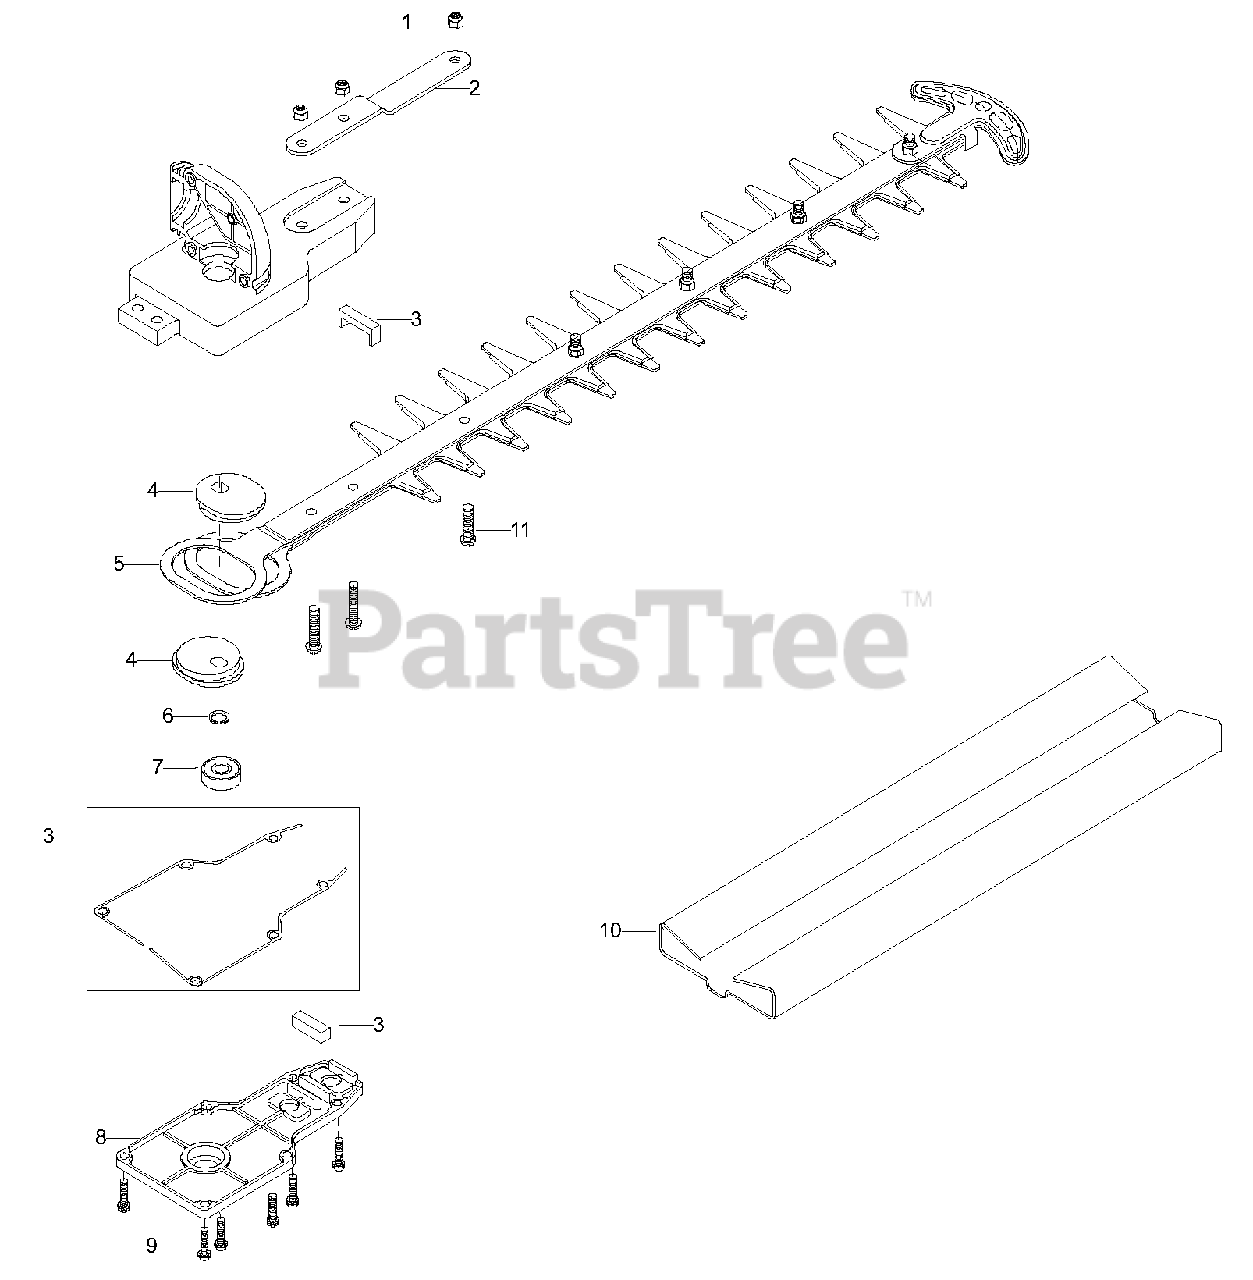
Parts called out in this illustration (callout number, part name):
1	NUT - PLATE RETAINING
2	PLATE 9102-A10601
3	KIT - GASKET
4	BLOCK - ECCENTRIC 9040-A10601
5	ASSEMBLY - BLADE 9228-A10610
6	C-RING 6CC-08
7	BEARING 6MB-607-01
8	COVER - BLADE HOUSING 9017-A10601
9	SCREW 6SQAZ-04-14
10	COVER - BLADE 9101-A10601
